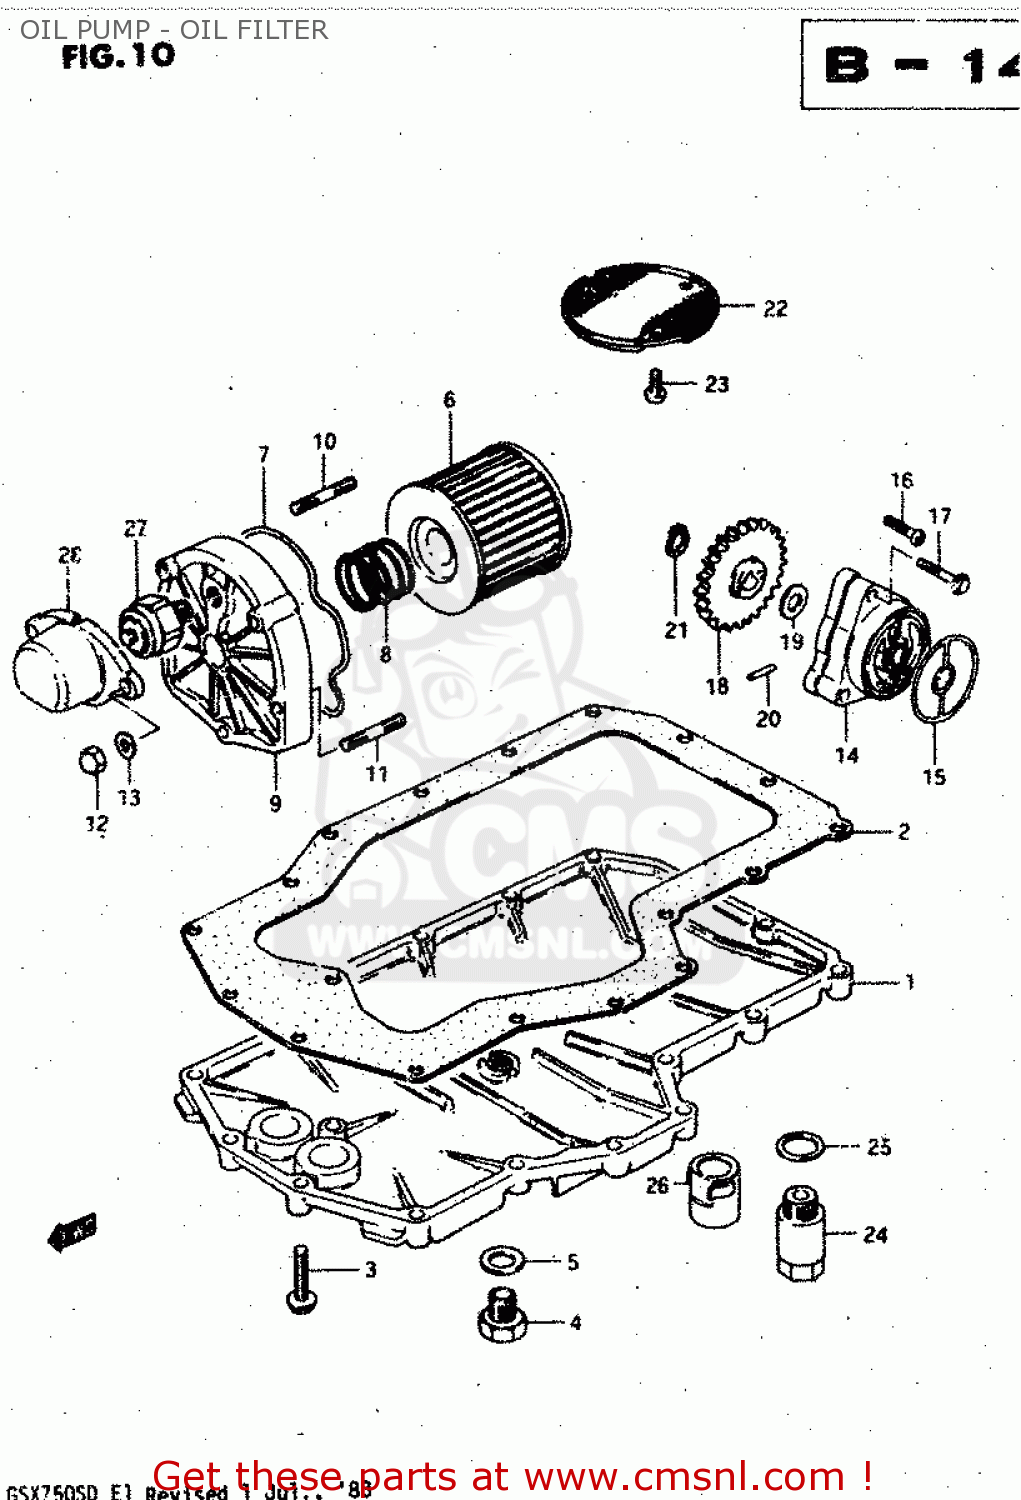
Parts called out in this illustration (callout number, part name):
1	PAN,OIL
2	GASKET,OIL PAN (MCA)
3	BOLT
4	PLUG
5	GASKET(14X19.2X2) (NAS)
6	FILTER ASSY,ENGINE OIL
7	O RING,OIL FILTER CHAMBER CAP
8	SPRING
9	CAP,ENGINE OIL FILTER
10	STUD 6X30
11	STUD 6X25
12	NUT
13	WASHER
14	PUMP ASSY,ENGINE OIL
15	O-RING,OIL PUMP
16	SCREW
17	BOLT(6X32)
18	GEAR,ENG OIL PUMP DRIVEN
19	SHIM
20	PIN(4X15.8)
21	CIRCLIP
22	STRAINER,ENGINE OIL
23	SCREW 6X12
24	VALVE ASSEMBLY,OIL RELIEF
25	WASHER
26	GUIDE, OIL REGULATOR
27	SWITCH ASSEMBLY
28	COVER,OIL PRESSURE SWITCH
